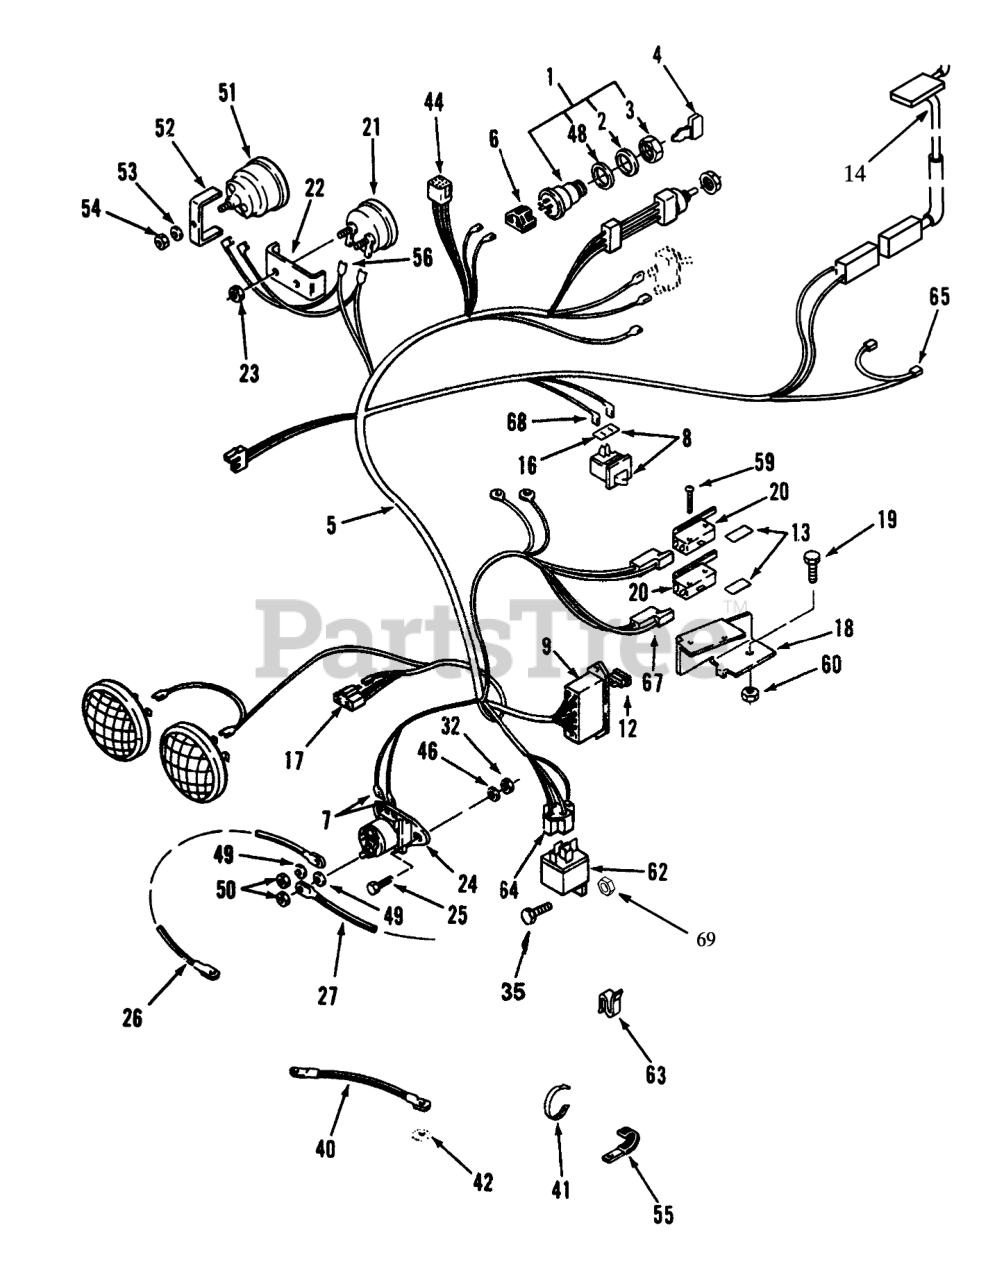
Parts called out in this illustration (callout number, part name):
1	KEY SWITCH ASM
2	LOCKWASHER
4	KEY-IGNITION
5	Harness Assy-Wiring (Inc Ref.#6, 7, 9, 44 & 64-68)
6	CONNECTOR BODY ELECT
7	TERMINAL 10
8	SWITCH INTERLOCK
9	FUSE-HOLDER 4 WAY
12	FUSE-BLADE, 15 AMP
13	BARRIER - SWITCH
14	SWITCH-SEAT
16	SHIELD-DIRT SPST
17	5-CONTACT CONN BODY
18	BRACKET-SWITCH
19	Bolt
20	SWITCH
21	VOLTMETER
22	CLAMP-MOUNTING
23	HEX NUT 10-32 E.S.
24	Solenoid
25	Screw
26	ASSY WIRE
27	CABLE-BLACK
40	WIRE GROUND
41	PLASTIC TIE
42	WASHER-LOCK, INTERNAL
44	Terminal
48	Washer
49	WASHER-LOCK
50	NUT-JAM
51	Meter-Hour (Incl. Ref.# 52-54)
52	BRKT-GAUGE MOUNTING
53	Lockwasher
54	Hex Nut
55	CLIP
59	Screw
60	NUT HEX 4-40 ELAST
62	RELAY
63	CLIP-CABLE
64	TERMINAL 10
65	Sur-Plug
68	Terminal
69	Nut
